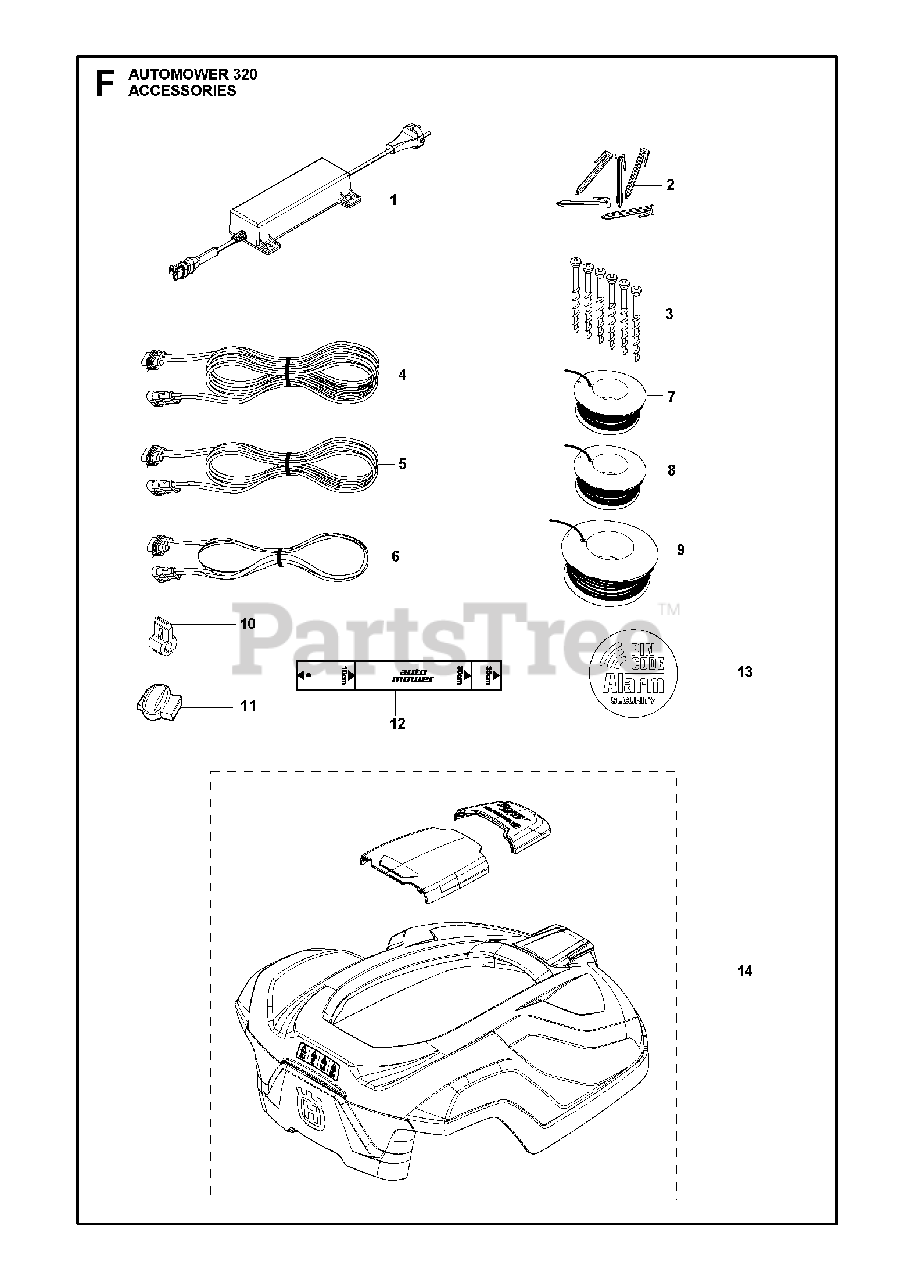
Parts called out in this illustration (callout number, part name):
2	STAPLES (100 CT BAG)
2	STAPLE 100 PCS BLISTE
3	SCREW KIT CS
3	SCREW 3 PCS, BLISTER PACK
4	LOOM LOW VOLTAGE CABLE 20 METE
5	LOOM LOW VOLTAGE CABLE 10 METE
6	LOOM LOW VOLTAGE CABLE 3 METER
7	LOOP WIRE 150M
7	WIRE 150M BLISTER
8	LOOP WIRE 250M
9	Wire, 500M
10	BRAKER
10	Connector, 5 Pcs Blist
11	SPLICE KIT
11	Splicer Coupler, 5 Pcs
11	SPLICE CONNECTOR 50 PCS/PK
12	RULER / CENTIMETERS
13	LABEL SECURITY
